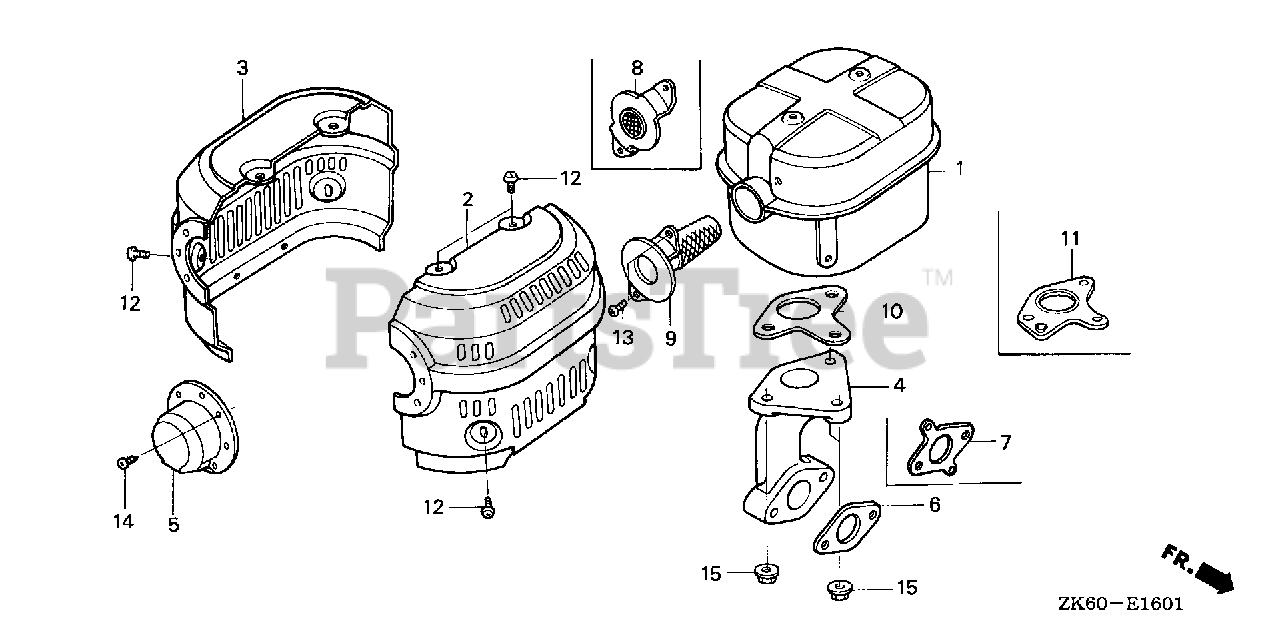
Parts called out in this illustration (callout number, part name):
2	PROTECTOR, R. MUFFLER
3	PROTECTOR, L. MUFFLER
7	GASKET, EX. PIPE
8	FLANGE, BAFFLE
10	GASKET, MUFFLER (NIPPON LEAKLESS)
12	SCREW, TAPPING (5X8)
13	SCREW, TAPPING (5X8)
15	NUT, FLANGE (8MM)
